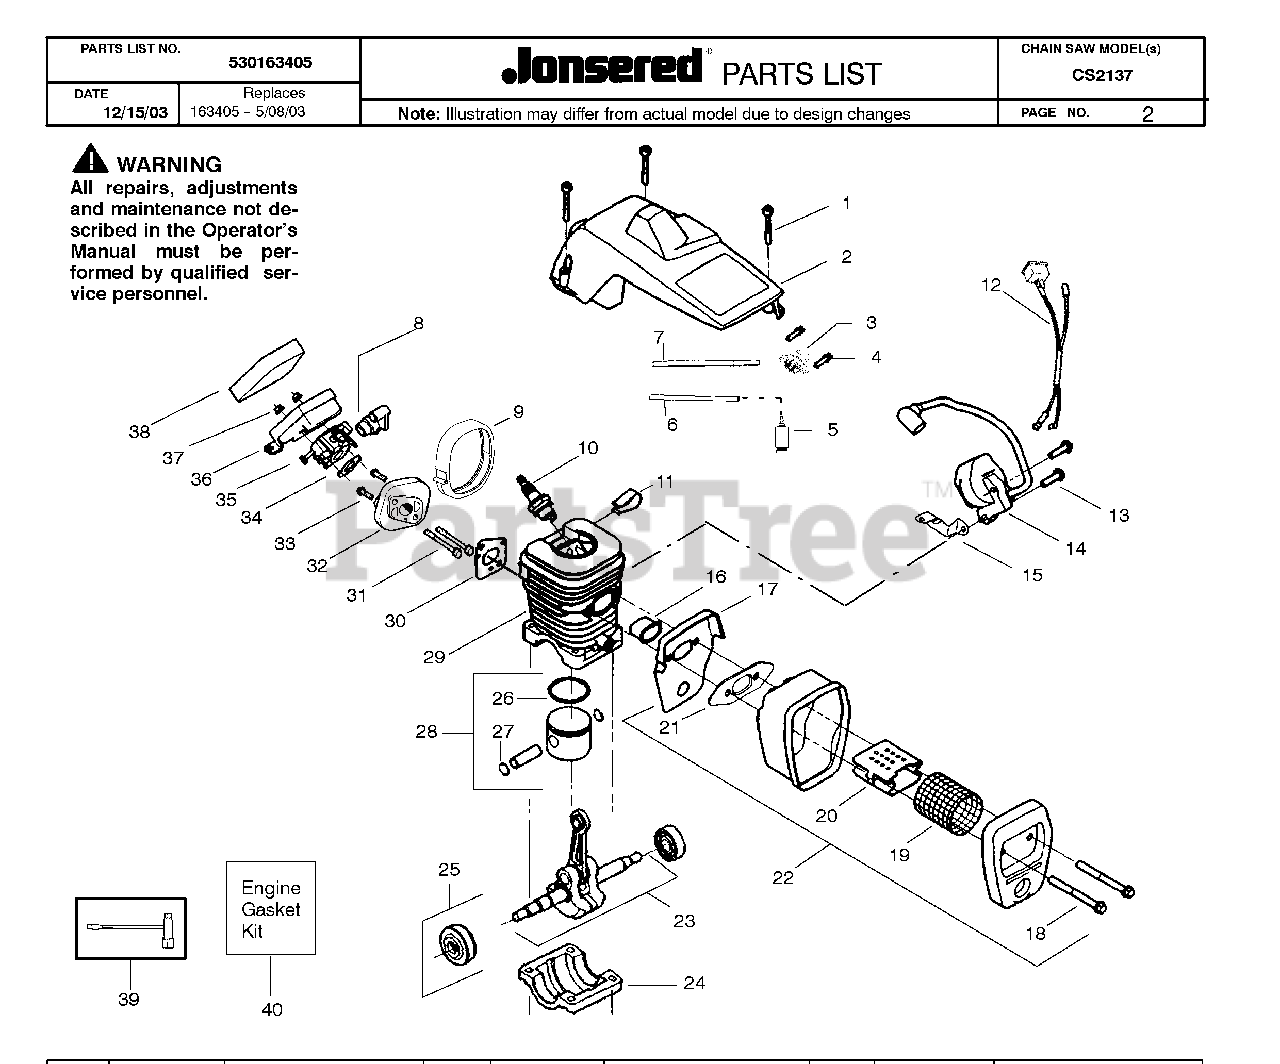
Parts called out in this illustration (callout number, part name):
2	CYL SHIELD ASSY
5	FUEL PICK-UP ASSY
8	GROMMET-CARB ADJUST
10	SPARK PLUG (RCJ-7Y)
12	WIRE HARNESS ASS'Y
14	MODULE-IGNITION
15	GROUND STRAP
16	HEAT INSULATOR
20	FLAME PROTECTION
22	MUFFLER
23	CRANKSHAFT
25	BEARING & SEAL ASSEMBLY
26	RING-PISTON
27	C-CLIP,PSTN PIN 36/41
29	KIT-CYLINDER
32	PARTITION
36	AIR FILTER HOUSING
38	AIR FILTER
39	SCRENCH
530038317	LIMITER CAP (LOW-BLUE)
530047630	DECAL STOP
530069722	CARBURETOR
530071621	KIT-CARBURETOR (WT-625)
